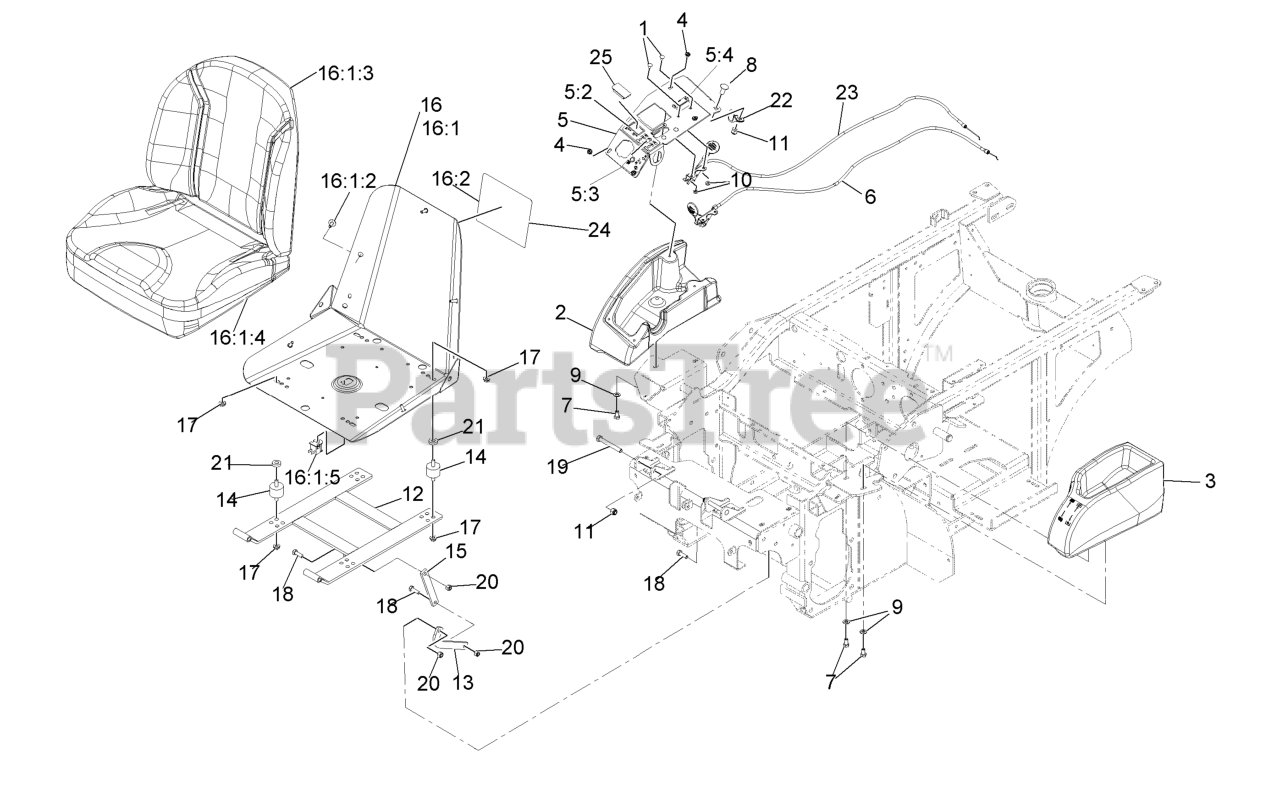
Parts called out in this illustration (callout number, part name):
1	Bolt-Carriage #10-24 X 1/2
2	Console-RH
3	Console, LH Grey
4	Screw-PPH #10-24 X 1/2
5	Control Panel ASM
5:2	Decal-Nav Console 640Kc
5:3	Decal-Speed Control
5:4	Decal-Choke
6	Cable-Throttle
7	Screw-HH 5/16-18 X 5/8
8	Bolt-Carriage 3/8-16 X 7/8
9	Washer-5/16 SAE
10	Nut-Nyloc #10-24
11	Nut-Nyloc 3/8-16
12	Frame-Seat
13	Link-Seat Stop
14	Mount-Vibration, Rubber
15	Link-Seat
16	ASM-Seat W/Decal
16:1	ASM-Seat, Navigator
16:1:2	Screw-HWH 1/4-20 X 3/4 Taptite
16:1:3	Cushion-Seat, Back
16:1:4	Cover-Seat Bottom Svc
16:2	Decal-Service Aid
17	Nut-Whizlock 5/16-18
18	Screw-HH 5/16-18 X 1
19	Screw-HH 3/8-16 X 3
20	Nut-Nyloc 5/16-18
21	Spacer
22	Clip-Loom
23	Cable-Choke
24	Decal-Service Aid
25	Plug-Hole
